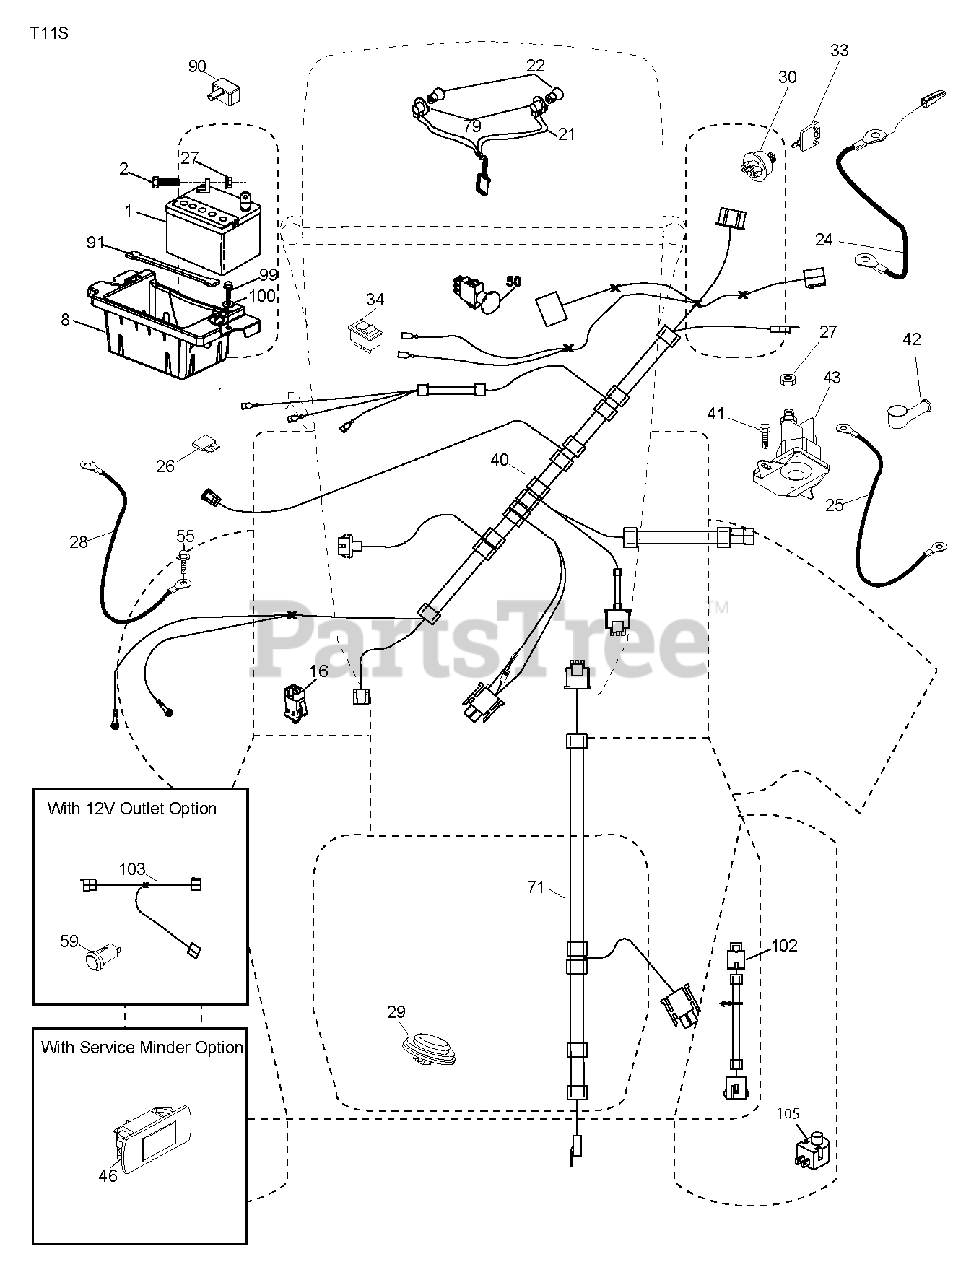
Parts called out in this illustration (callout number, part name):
1	Battery, Dry 30 Amp
2	BOLT.HEX.1/4.X.3/4.DICHROMATE
8	BOX.BATTERY.MOUNT.FRONT.LT
16	SWITCH INTERLOOK PUSH-IN
21	HARNESS.LIGHT W/4152J BULBS
24	CABLE.BATT.POS.WIRE.TG.DA SOL
25	CABLE.STARTER.6G.BL/RED.17.5
26	FUSE 20AMP
27	NUT
28	CABLE GROUND 6 GA 21" 90T BLK
29	SWITCH.SEAT.DELTA.OPC.
30	SWITCH.IGN.DELTA.W.LGH.ROS
33	KEY.CHAIN.BLISTER.PACK.GEN.INT
40	HARNESS-CHASSIS SUB
41	SCREW
42	TERMINAL COVER
43	SOLENOID.W/BRASS.PLUNGER
46	RP GUAGE.SRVCMNDR.HRMTR.
50	RB PTO.SWITCH.8 TERMINAL.BLACK
55	SCREW 5/16"
71	HARNESS.IGN.DASH.HUQ/P
79	BULB HOLDER ASM.
90	COVER.TERMINAL.BATTERY
91	STRAP.BATTERY.MOUNT.FRONT(2 2)
99	SCREW HEXWSHR 1/4-20X3/4
102	REVERSE SWITCH
105	HARNESS PIGTAIL PCH TEX ROS
